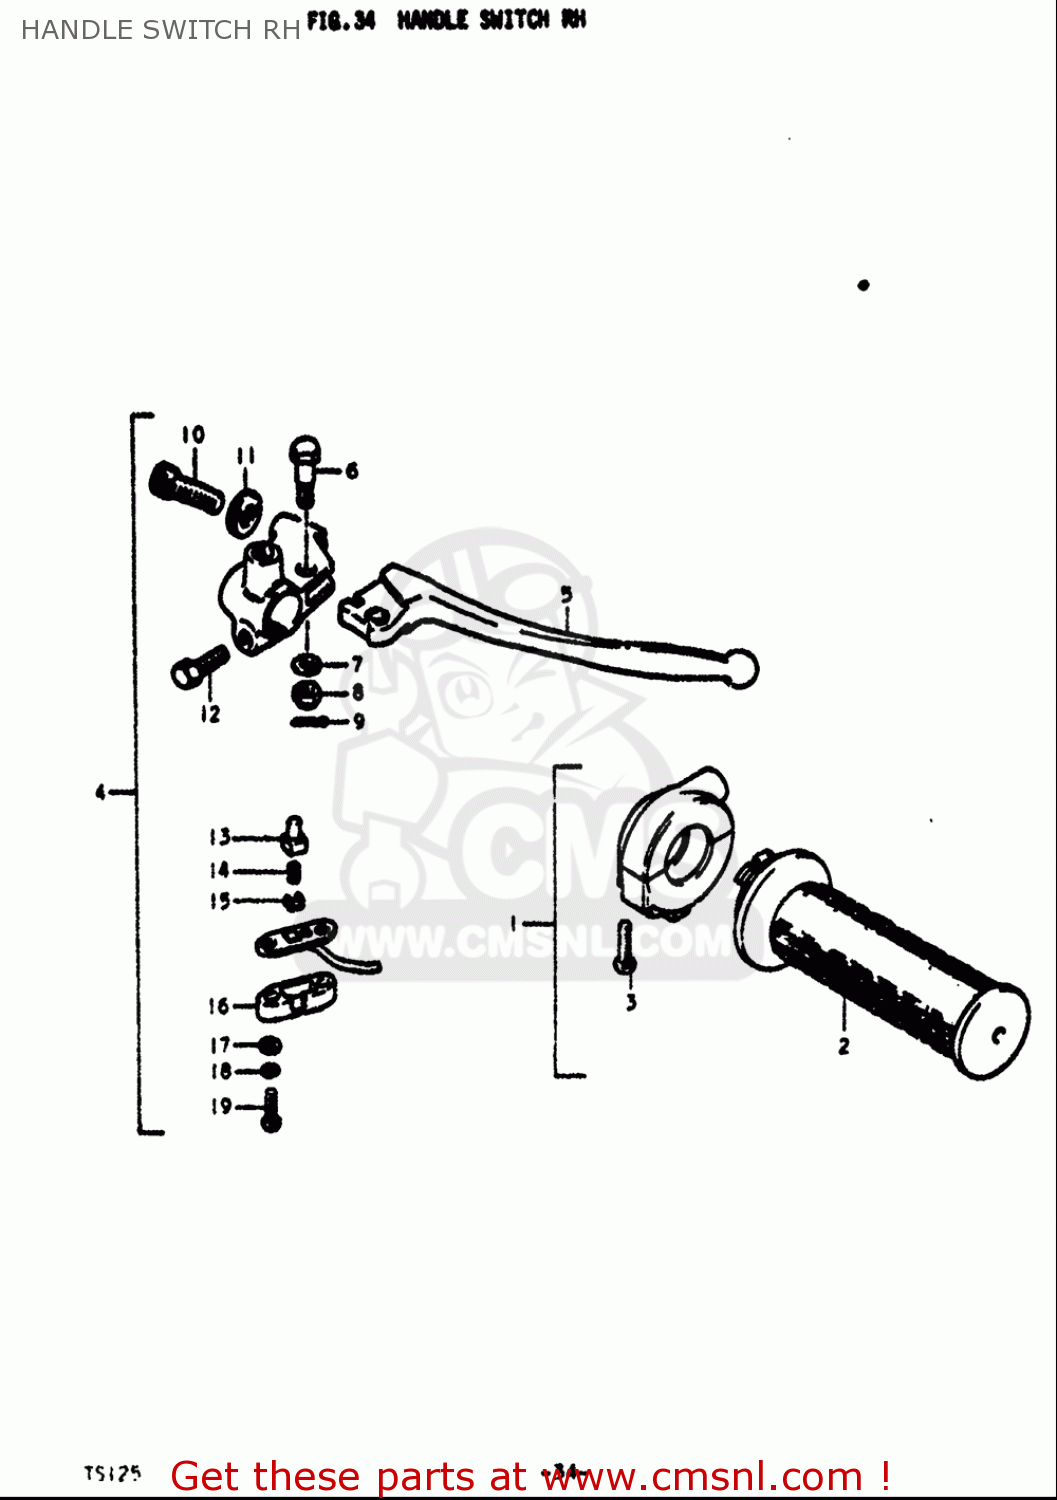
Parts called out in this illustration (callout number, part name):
1	GRIP ASSY,THROTTLE
2	GRIP,THROTTLE
3	SCREW
4	BRAKE LEVER & SWITCH ASSY
5	LEVER,BRAKE
6	BOLT,LEVER PIVOT
7	WASHER,LOCK
8	NUT,LEVER FITTNG
9	PIN 16X20
10	ADJUSTER,CABLE
11	NUT,CABLE ADJUSTER
12	BOLT
13	CONTACT,SWITCH
14	CONTACT,SWITCH
15	CONTACT,SWITCH
16	COVER,FR BK TERMINAL BASE
17	WASHER
18	WASHER,LOCK
19	SCREW
